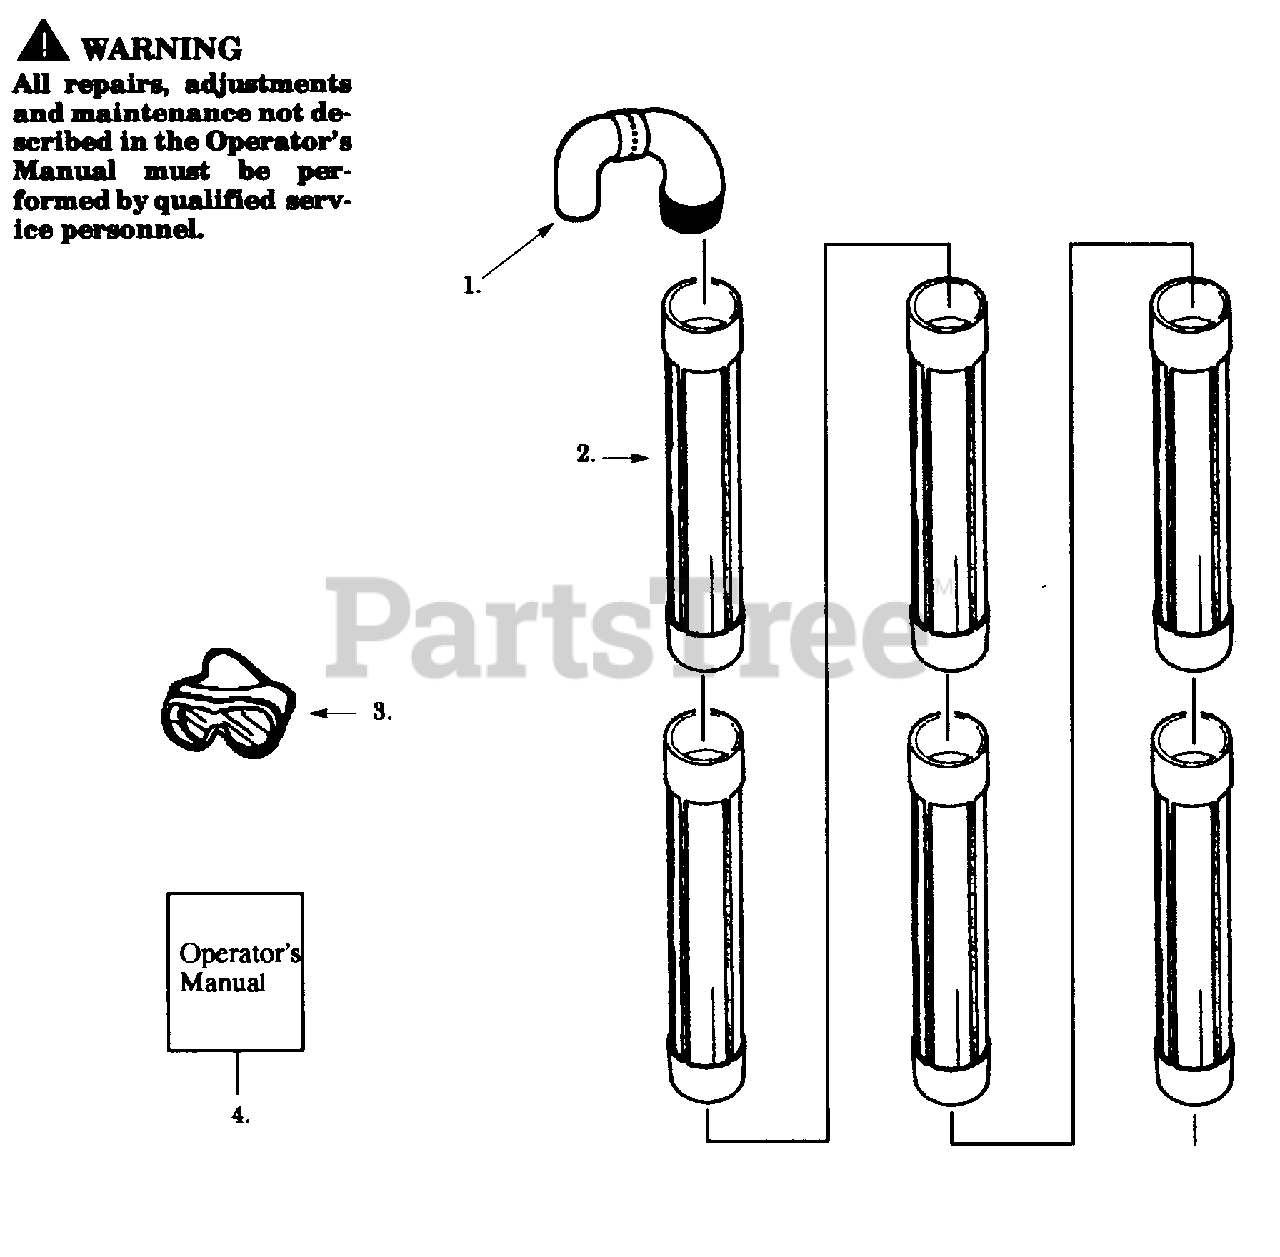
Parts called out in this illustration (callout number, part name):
1	Nozzle Ass'y.
2	Outlet Tube (1 of 6)
3	Safety Goggles
4	Operator Manual
